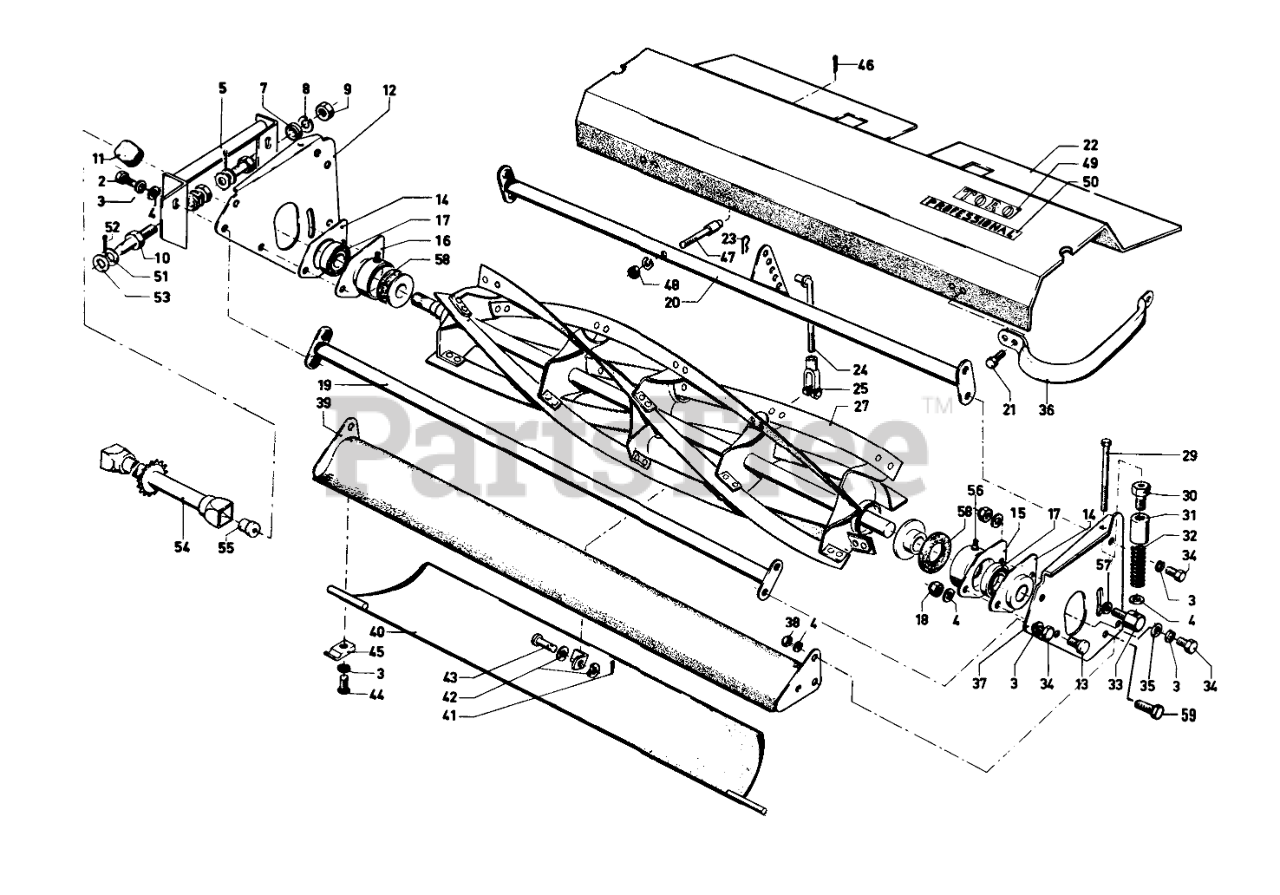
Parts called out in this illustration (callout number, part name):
2	SCREW-HH
3	WASHER-LOCK, INTERNAL
4	WASHER-PLAIN
7	SPHERICAL SPACER
8	WASHER-LOCK
9	NUT-HEX
10	PIVOT STUD
13	BEARING CUP BOLT
18	NUT-LOCK
21	10-16 X 3/8 THDG SCREW
23	PIN-COTTER
25	YOKE
30	Bolt-Adjusting
31	ADJUSTMENT BLOCK
33	REEL BEARING SCREW
34	SCREW-HH
35	WASHER-FLAT
38	NUT-HEX
41	PIN-COTTER
42	WASHER-SPRING
43	PIN-CLEVIS
45	CLIP-SKID
46	PIN-COTTER
50	Decal
51	9/16ID X 032 WASHER
52	PIN-COTTER
53	COLLAR
56	FITTING-GREASE
57	WASHER
58	1 X .250 OIL SEAL
59	SCREW-HH
